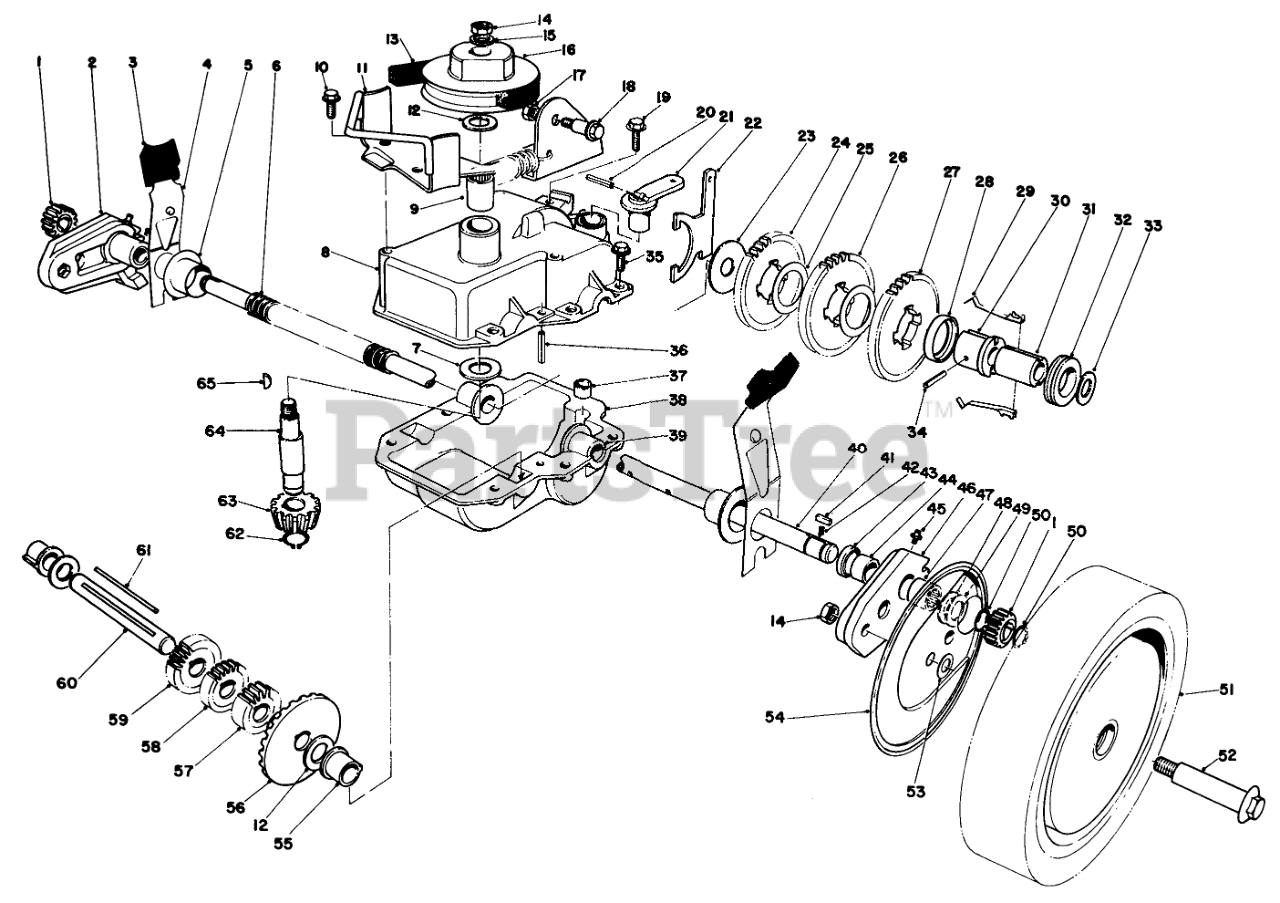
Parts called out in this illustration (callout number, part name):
1	GEAR-PINION
2	Pivot Arm Assy. R.H. (Incl. Ref. #43-45 & 47)
3	KNOB-ARM
4	SPRING ARM ASM SP
5	CAP-END
6	CONDUIT-CONVOLUTED, SPLIT
7	Thrust Washer
8	Case-Upper
9	Bearing
10	SCREW
11	Belt Guide Bracket
12	WASHER-THRUST
13	V-BELT
14	Nut
15	WASHER-FLAT
16	PULLEY
17	NUT-LOCK, CONE
18	SHOULDER BOLT
19	SCREW-HWHTF
20	PIN-COIL
21	LEVER-SHIFT
22	Shift Yoke
23	WASHER
24	GEAR-38T
25	WASHER
26	Gear-40 Tooth
27	GEAR-42T
28	KEY RETAINER
29	Key
30	Body-Sleeve
31	SLEEVE
32	COLLAR-SHIFT
33	WASHER-PLAIN
34	PIN-SPRING
35	SCREW-HWH, THREAD ROLL
36	ROLL PIN 3/16 X 1 IN
37	BUSHING-YOKE
38	LOWER GEAR CASE CAST
39	Bushing
40	Output Shaft
41	KEY RECTANGULAR
42	SPRING-COMPRESSION
43	Seal
44	Bushing
45	FITTING-GREASE
46	Pivot Arm Assy. L.H. (Incl. Ref. #43-45 & 47)
47	Needle Baring
48	Washer
49	THRUST WASHER
50	RING-RETAINING
51	Wheel & Tire Assy.
52	BOLT-WHEEL
53	WASHER
54	WHEEL COVER
55	Botching Shaft
56	BEVEL GEAR
57	14 T GEAR
58	16 T GEAR
59	GEAR-18T
60	Sort Shaft
61	Key Square
62	RING-RETAINING
63	PINION-BEVEL
64	INPUT SHAFT
65	KEY-WOODRUFF
